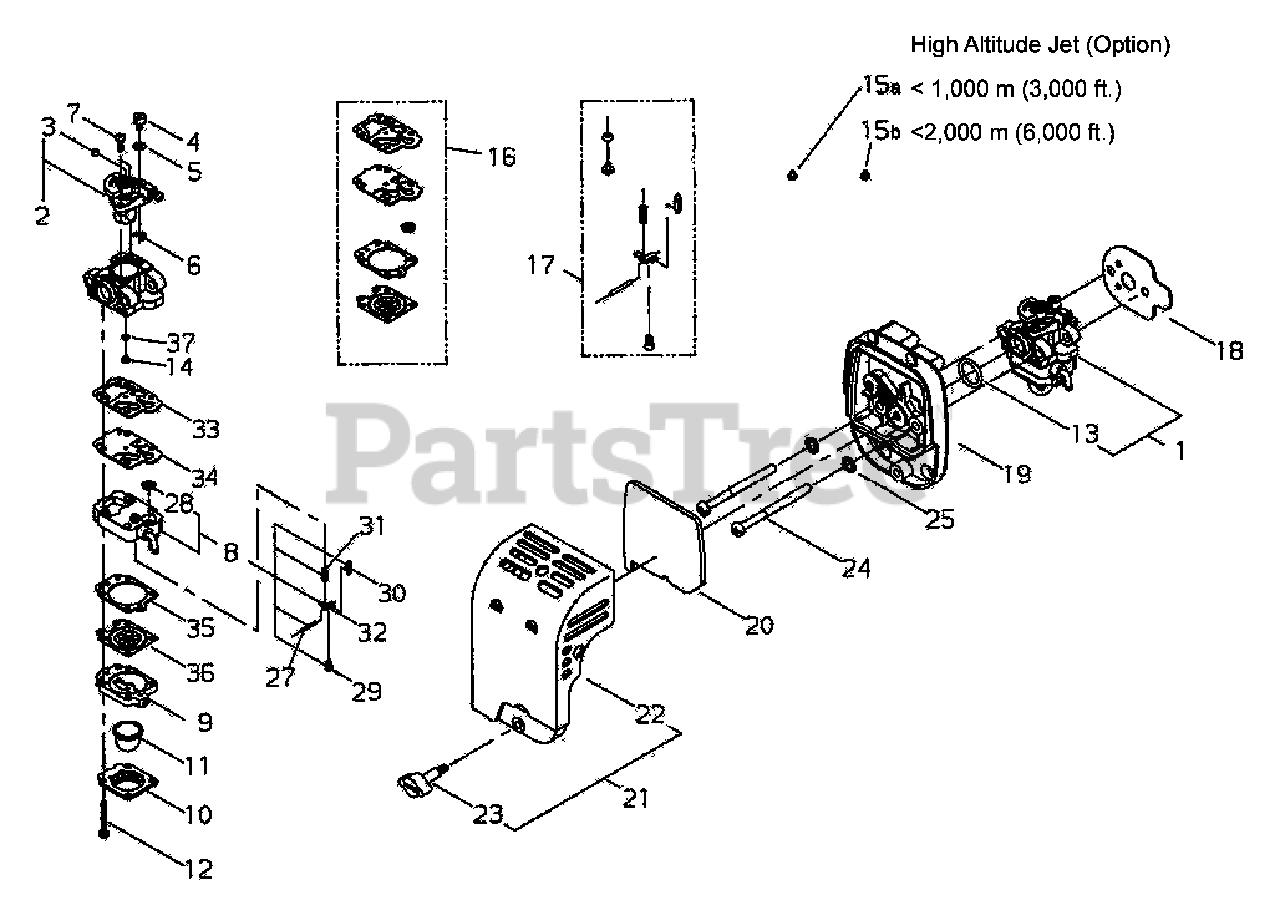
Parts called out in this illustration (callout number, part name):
1	CARBURETOR
2	JET, MAIN
3	PLUG
4	SWIVEL
5	WASHER
6	E-RING
7	SCREW, THROTTLE COLLAR
8	BODY ASSY, PUMP
9	BODY ASSY, PURGE
10	RETAINER, PURGE BULB
11	BULB, PURGE
12	SCREW
13	O-RING 15
14	JET, MAIN
16	GASKET / DIAPHRAGM KIT
17	VALVE KIT, INLET NEEDLE
18	GASKET, INTAKE
19	CASE ASSY, AIR FILTER
20	FILTER, AIR
21	COVER ASSY, AIR FILTER
22	COVER ASSY, AIR FILTER
23	COVER, AIR FILTER
24	SCREW M5×60
25	WASHER 5 MM
27	PIN, METERING LEVER
28	SCREEN, FUEL INLET
29	SCREW
30	VALVE, INLET NEEDLE
31	SPRING, METERING LEVER
32	LEVER, METERING
33	GASKET, PUMP
34	DIAPHRAGM, PUMP
35	GASKET, METERING DIAPHRAGM
36	DIAPHRAGM, METERING
37	O-RING
